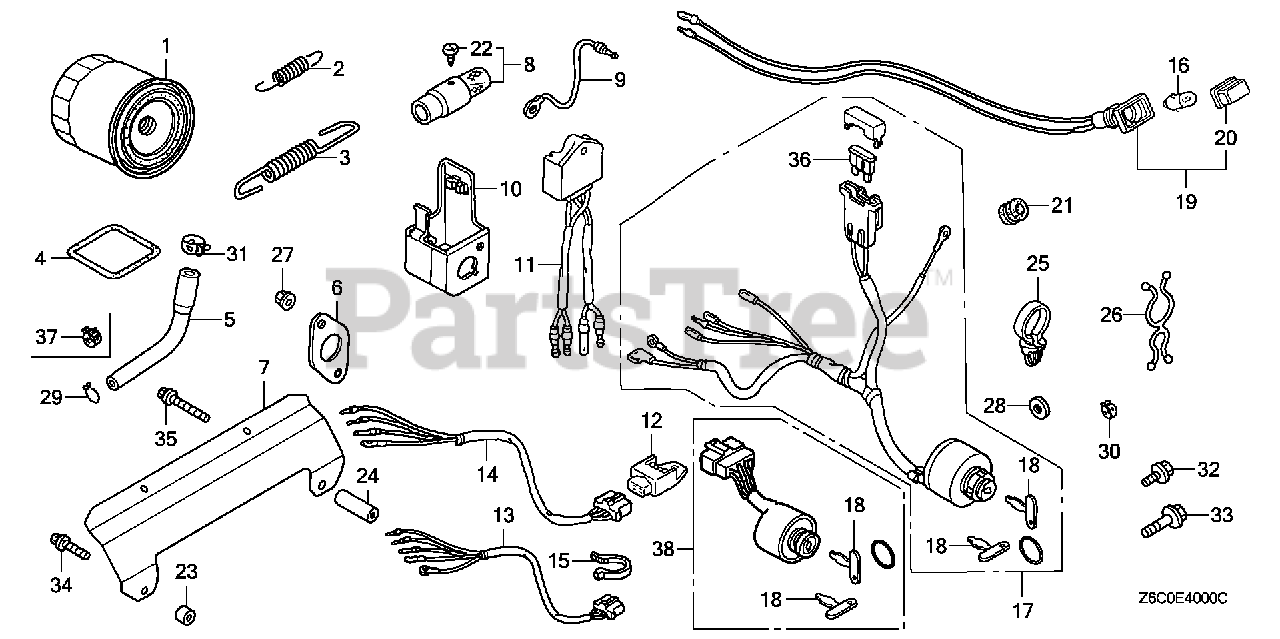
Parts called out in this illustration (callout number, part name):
16	BULB, WEDGE BASE (12V/2W)
19	SOCKET ASSY., LAMP (RED)
20	LENS (RED)
